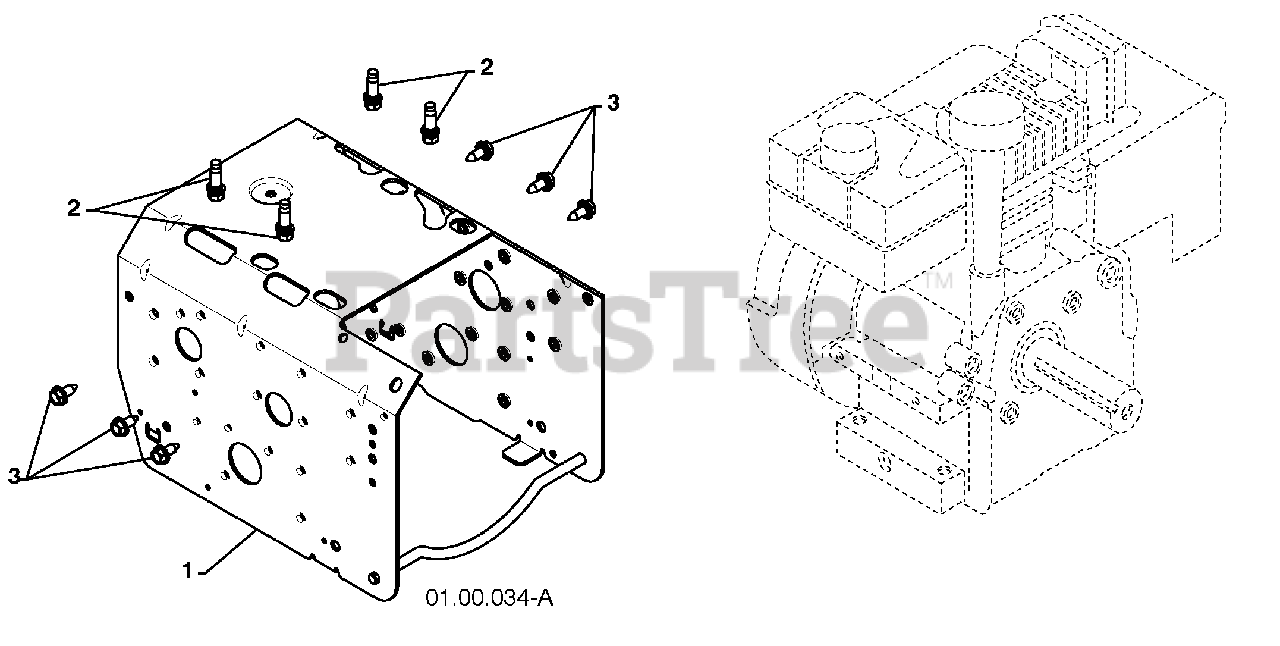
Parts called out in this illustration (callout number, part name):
1	FRAME
2	BOLT 3/8-16
3	SCREW 5/16-18 X .750
